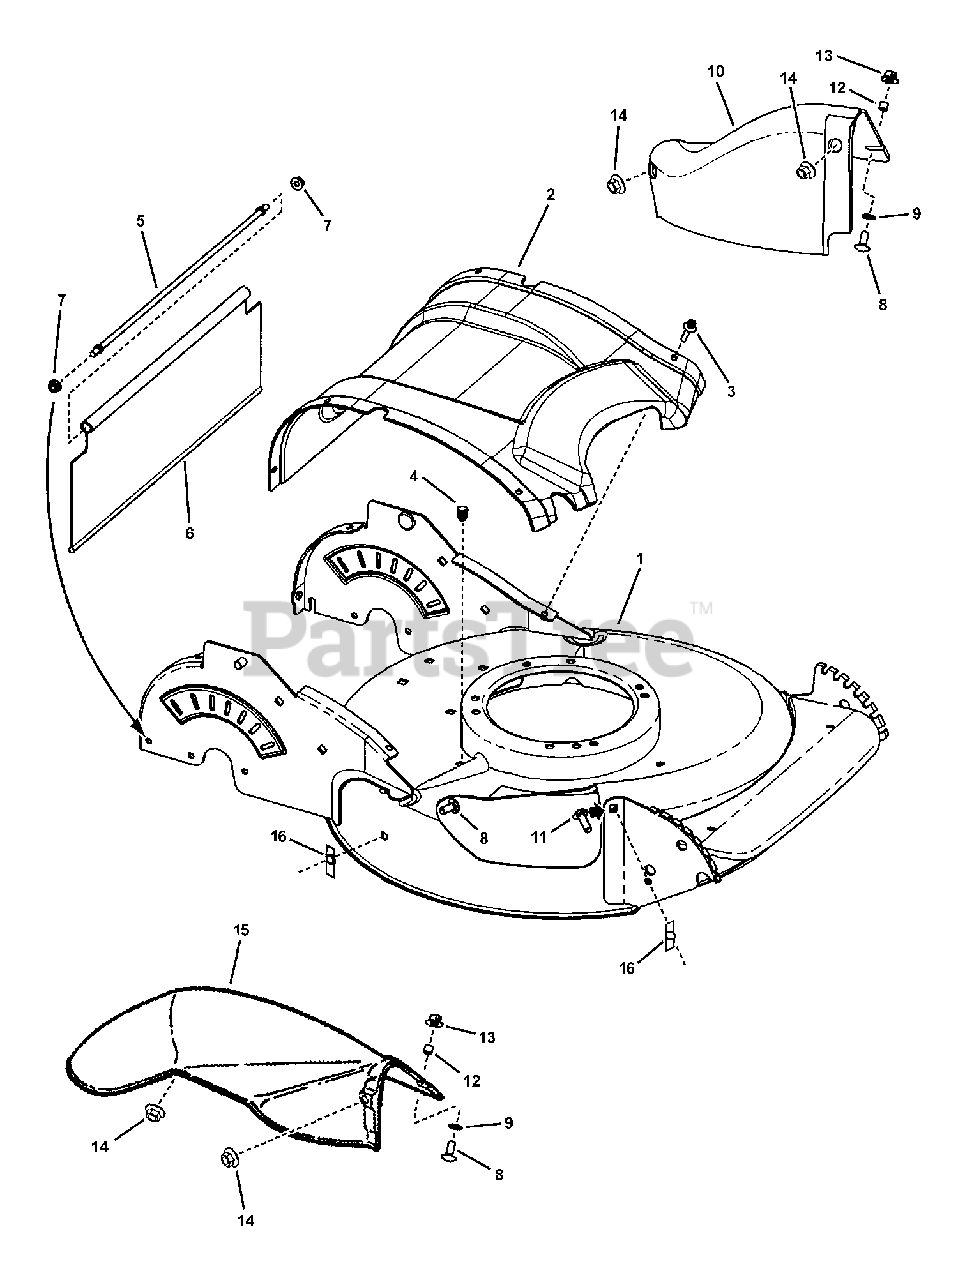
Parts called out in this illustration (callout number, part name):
1	WELDMENT, 21" Deck, 7 Position
2	REAR COVER, Belt/Transmission
3	SCREW, 7 mm x 1 x .55 AB Point
4	PLUG, Hole (Polyethylene)
5	ROD, Trail Shield
6	SHIELD, Trail
7	NUT, 1/4-20 Hex Flange Lock
8	BOLT, 5/16-18 x 3/4" Short Square Neck Carriage, GR 5
9	BOLT RETAINER, 5/16- Black
10	COVER, 21 Deck Recycling
11	BOLT, 5/16-18 x 1-1/8" Short Square Neck Carriage, GR 5
12	SPACER, .316 x .375 x .300/.310
13	NUT, 5/16-18 Large Flange Hex Center Lock
14	NUT, 5/16-18 Hex Flange Lock
15	CHUTE, 21 Side Discharge
16	NUT, 5/16-18 Speed
